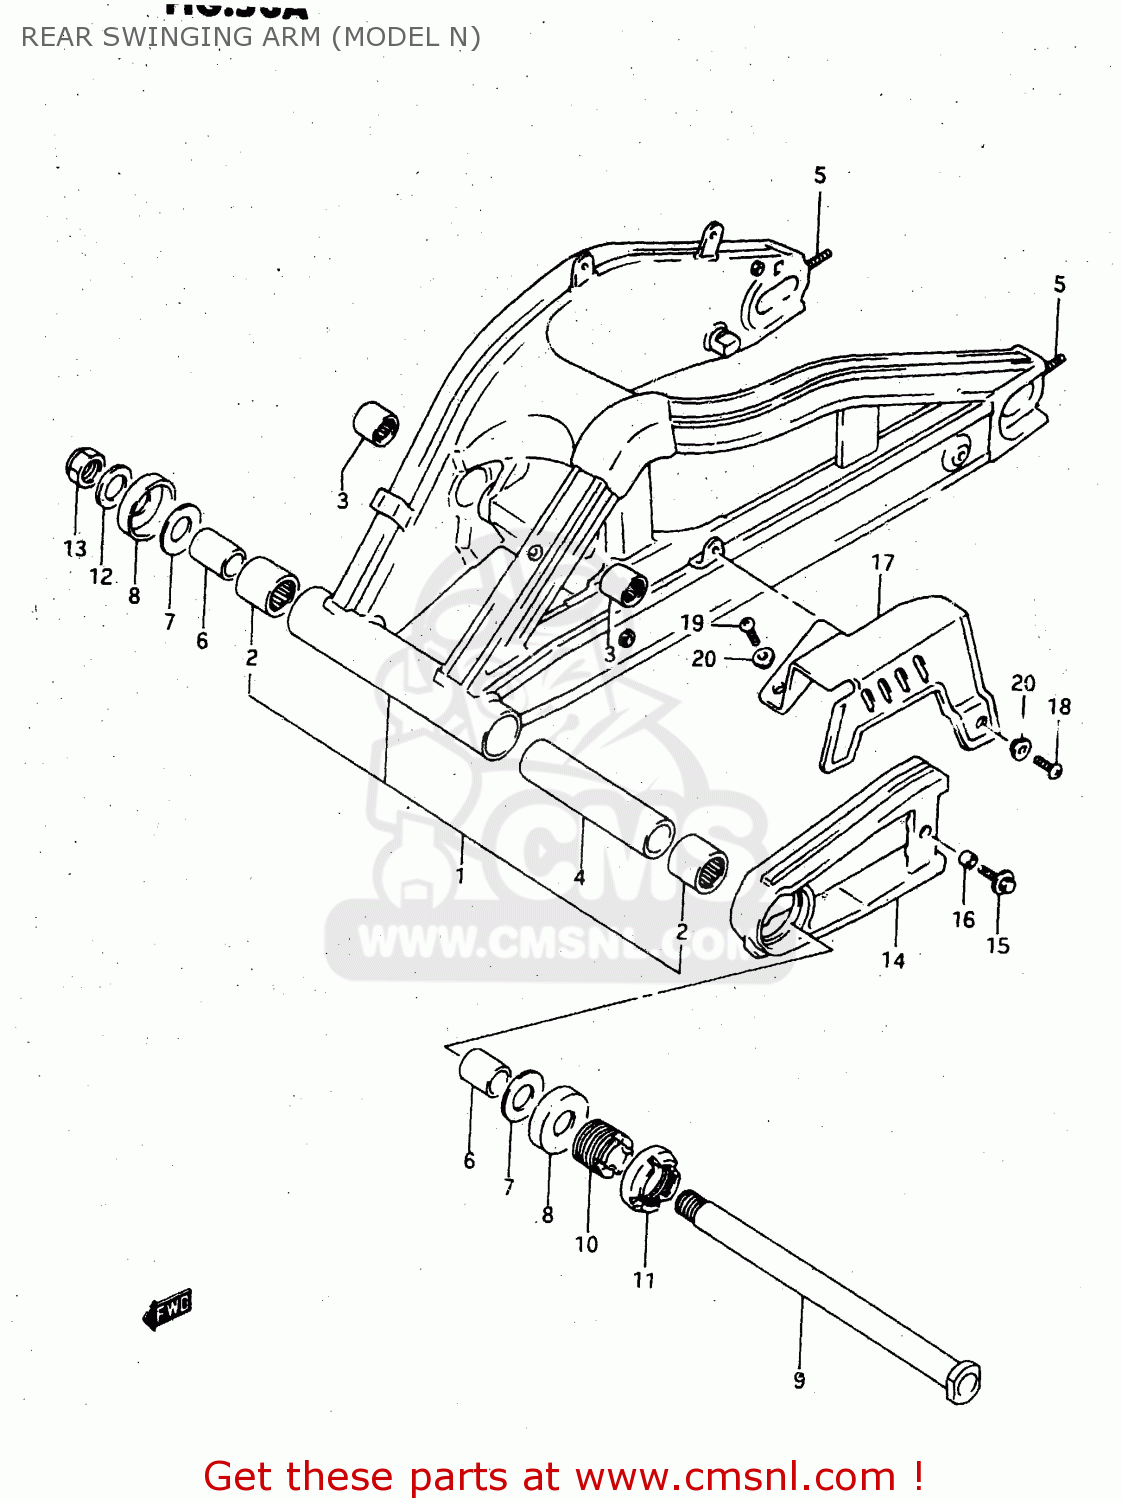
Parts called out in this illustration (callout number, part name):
1	SWINGING ARM ASSY, REAR
2	BEARING(25X33X30)
3	BEARING(17X24X20)
4	SPACER,RR SWGARM PIVOT CTR
5	STUD,CHAIN ADJUSTER BOLT
6	SPACER,RR SWGARM PIVOT BERRING
7	WASHER
8	DUST SEAL,RR SWGARM PIVOT
9	SHAFT,RR SWINGINGARM PIVOT
10	BOLT,RR SWGARM PIVOT
11	NUT,REAR SWING ARM PIVOT
12	WASHER
13	NUT
14	BUFFER,CHAIN TOUCH DEFENSE
15	BOLT 6X20,WITH PLAIN WASHER
16	SPACER
17	CASE,CHAIN
18	SCREW
19	SCREW, CENTER
20	WASHER
